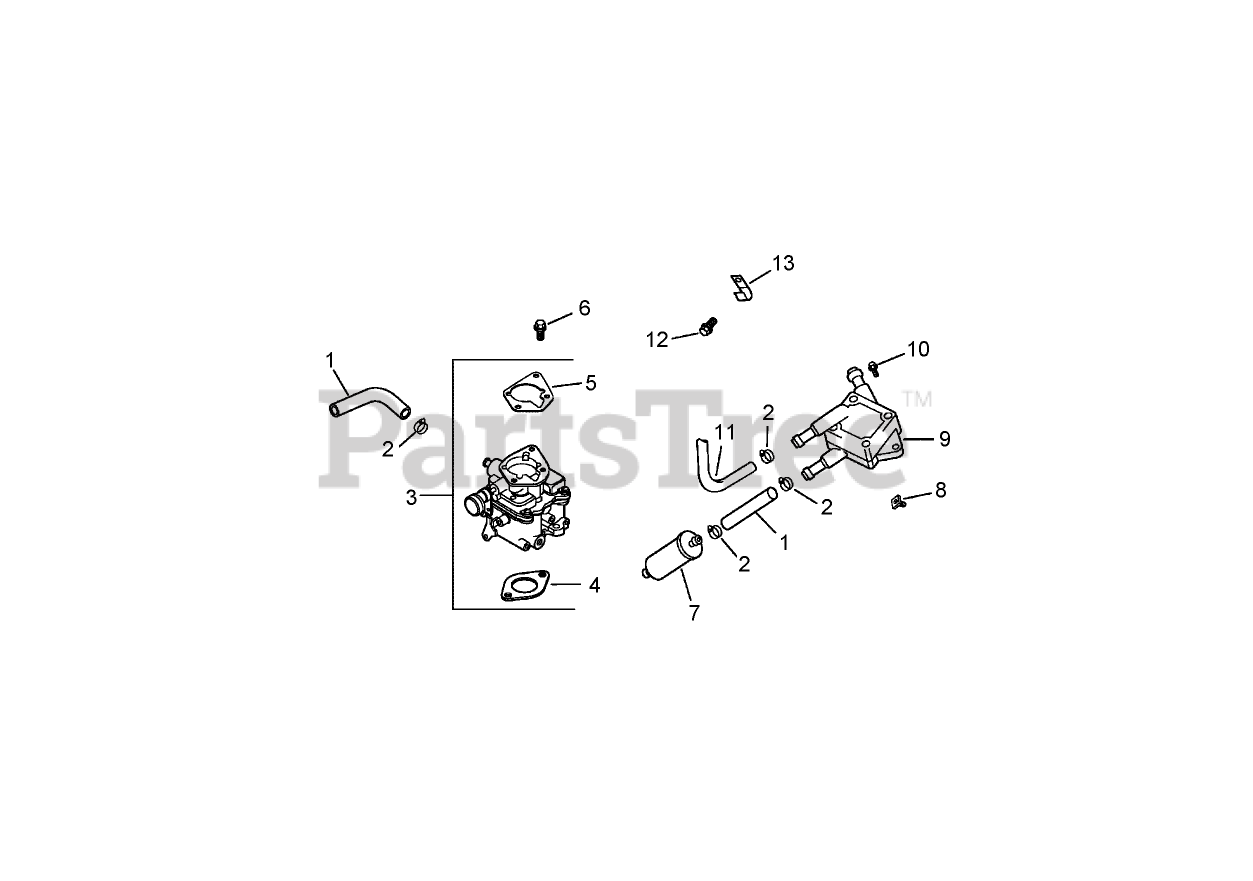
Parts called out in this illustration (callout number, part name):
1	Line-Fuel (9.5)
2	CLAMP-HOSE, SPRING (1/2)
3	Carburetor Kit (Includes 4, 5)
4	Gasket-Carburetor
5	GASKET-BASE, AIR CLEANER
6	SCREW-FLANGE (M6X1.0X30)
7	Filter-Fuel
8	Nut-Plastic
9	PUMP-FUEL
10	SCREW-TAP (M6X1.7X18)
11	Line-Fuel, Flexible (15.5)
12	Screw-HF (M6x1.0x12)
13	CLIP-CABLE
